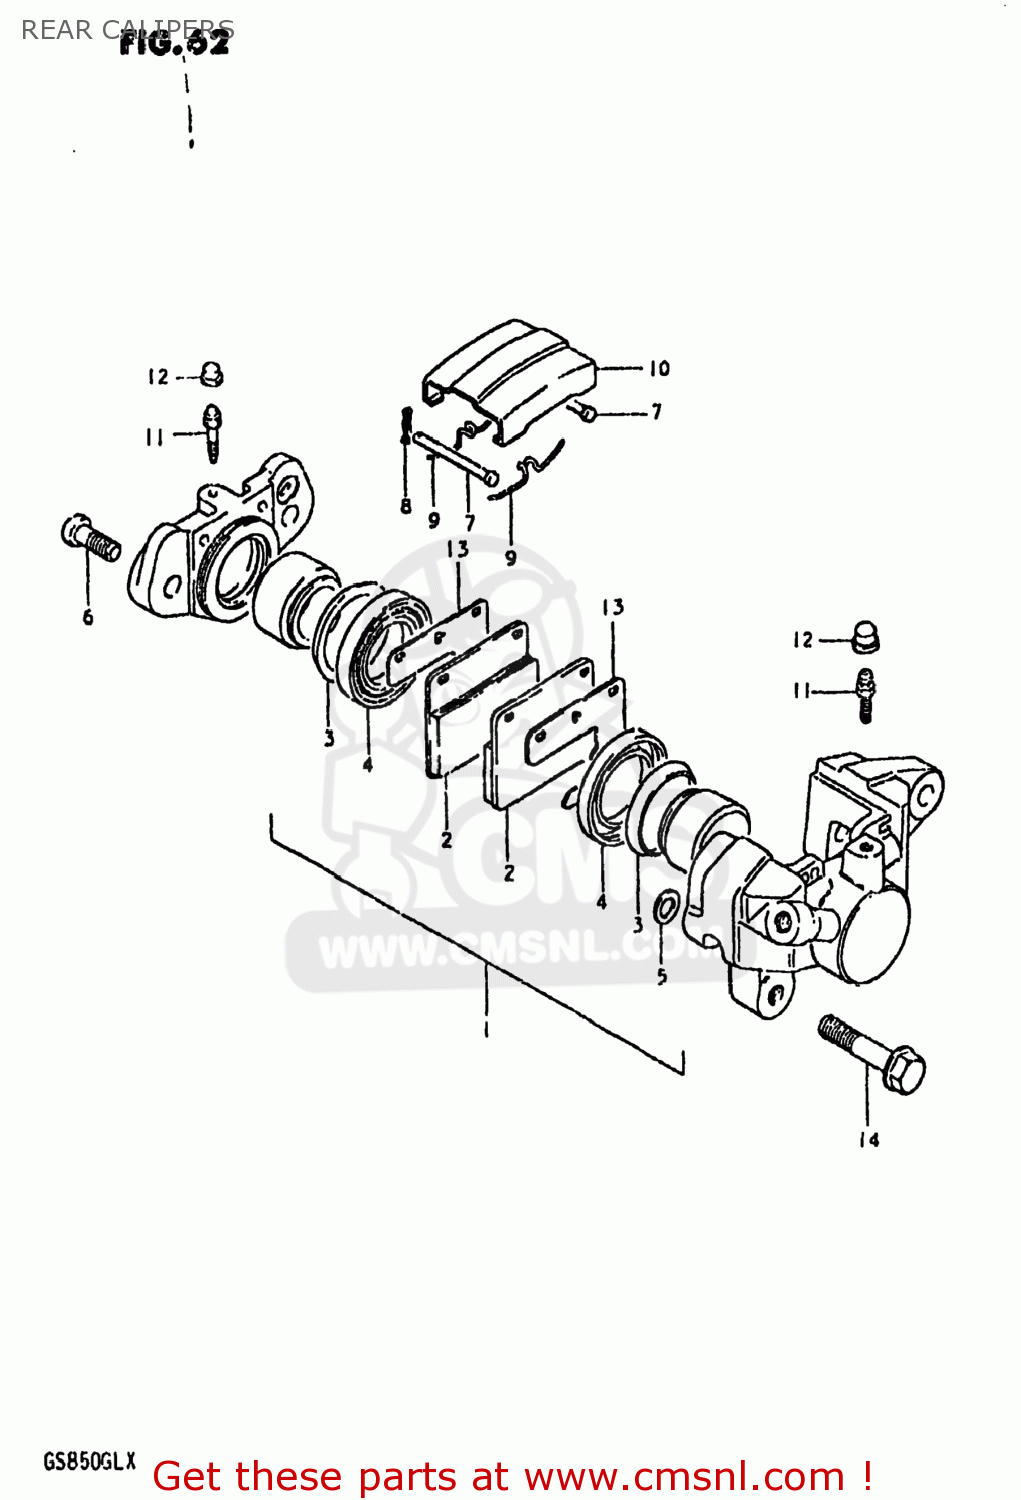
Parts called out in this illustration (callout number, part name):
1	PISTON SET
2	PAD,BRAKE
3	SEAL,PISTON
4	BOOT,PISTON
5	SEAL,PISTON
6	BOLT,HOUSING
7	PIN,PAD
8	CLIP,PAD PIN
9	SPRING
10	COVER,DUST
11	BLEEDER
12	CAP,BREATHER
13	SHIM,RR CALIPER
14	BOLT
